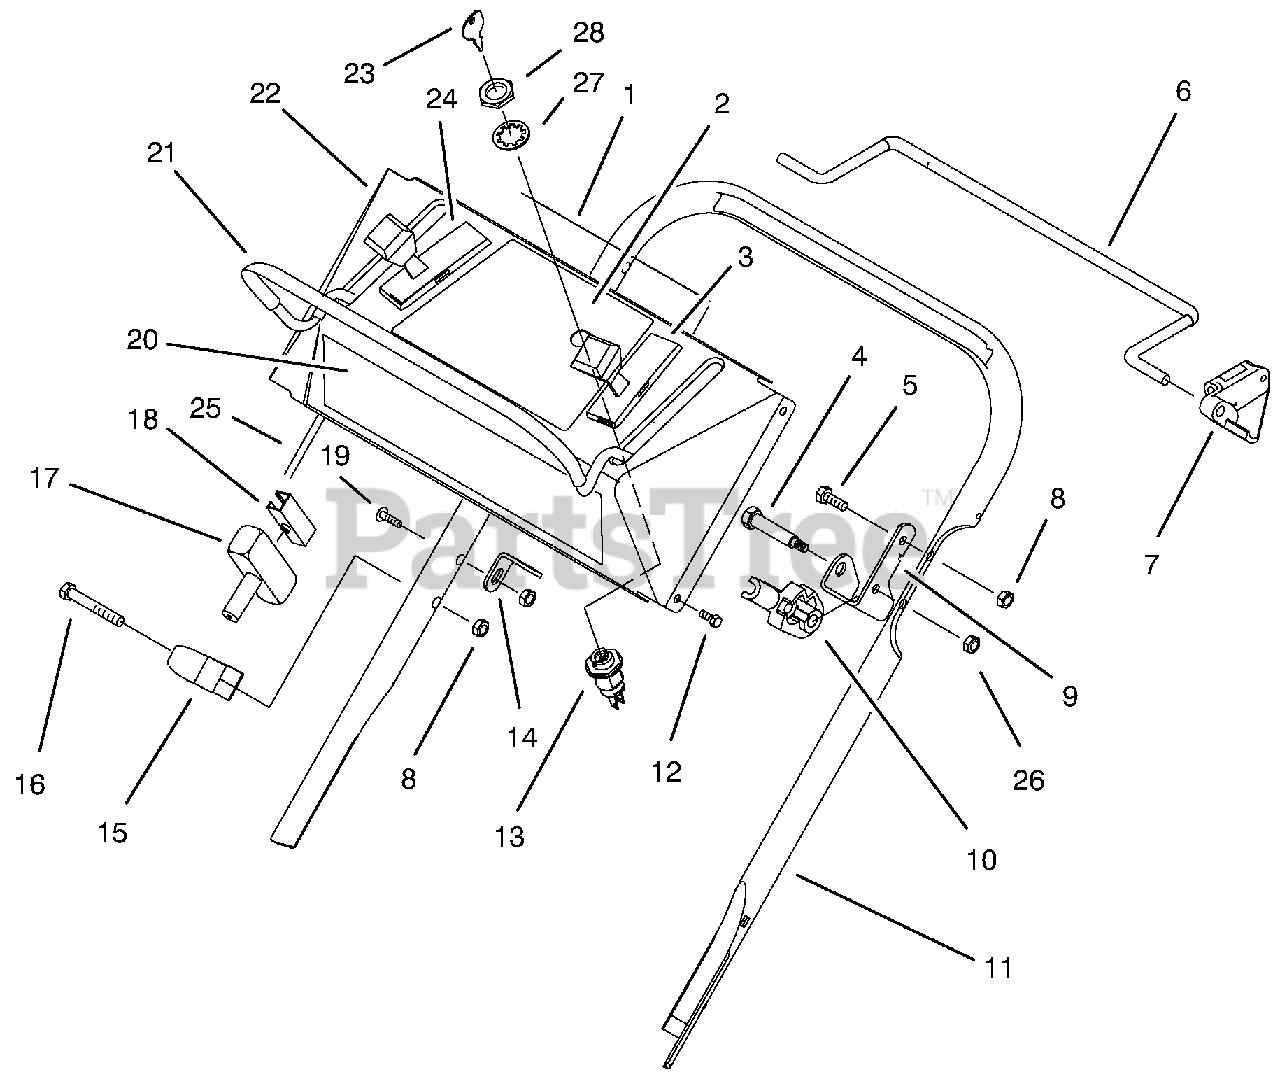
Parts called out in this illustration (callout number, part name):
1	Decal-Warning
2	Decal-Warning
3	Cable-Throttle
5	Screw-Hex Hd. Cap
6	Bail-Control S.R
7	Stop-Pivot
8	Nut-Lock
9	Bail-Stop Bracket
10	Cam-Brake
11	Handle-Upper
12	Screw-Phillips Hd.
13	Switch-Starter
14	Bracket-Cable Anchor
15	Guide-Rope
16	Screw-Hex Hd. Cap
17	Handle-Starter
18	Clip-Rope Insert
19	Screw-Handle
20	Decal-Console Front
21	Bail-Engine Control
22	Panel-Control (Incl. Ref. #1, 2, & 20)
23	Key
24	Control-Ground Speed
25	Cable-Control
26	Nut-Lock
27	Washer-Star
